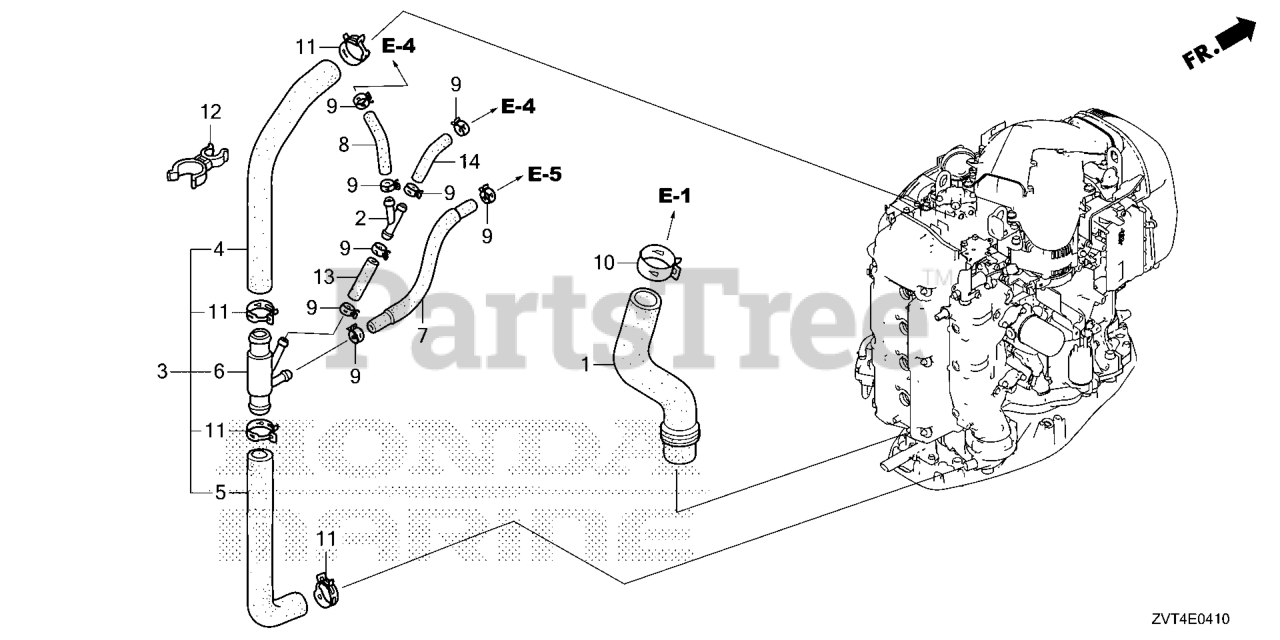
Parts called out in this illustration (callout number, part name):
2	JOINT, FUEL TUBE
3	TUBE, WATER RELIEF
4	TUBE A, WATER RELIEF
5	TUBE B, WATER RELIEF
6	JOINT, FOUR-WAY
7	TUBE E, WATER
8	TUBE COMP, WATER
9	CLAMP, TUBE (D10.5) (ENGINE NO.)
10	CLAMP, TUBE (D32.5)
11	CLAMP, TUBE (D25.0)
12	CLAMP, WATER TUBE
13	BULK HOSE, VACUUM (7X3000) (7X550)
14	BULK HOSE, VACUUM (7X3000) (7X550)
